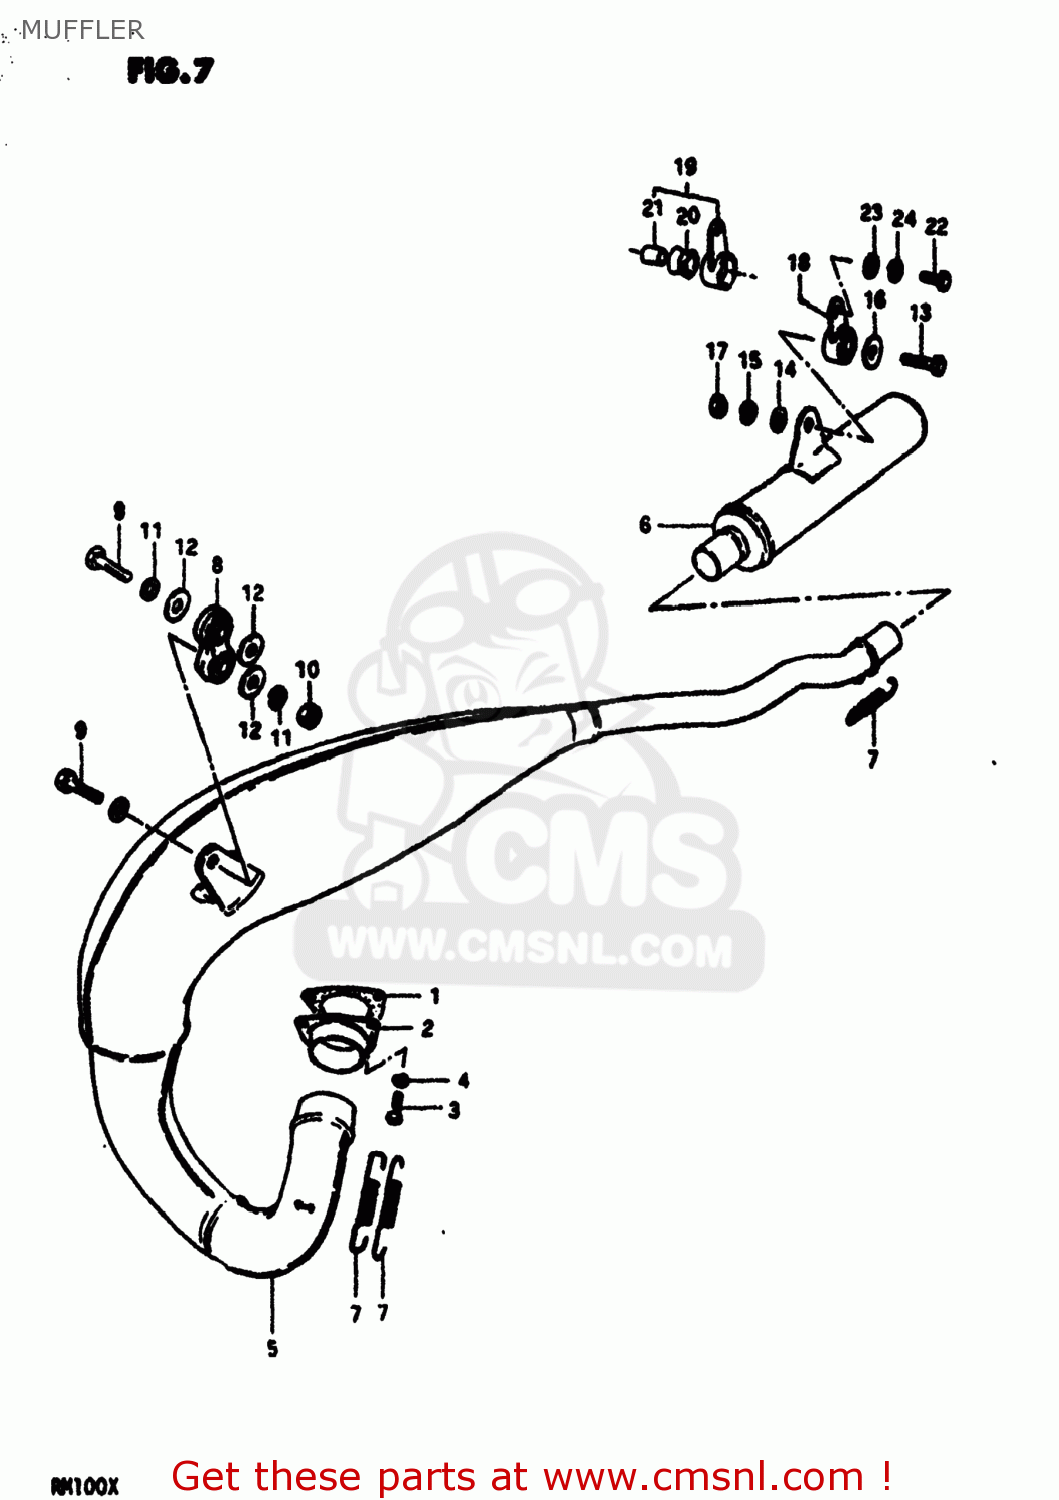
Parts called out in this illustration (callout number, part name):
1	GASKET,EXHAUST PIPE (MCA)
2	FLANGE,EXHAUST PIPE
3	SCREW
4	LOCK WASHER
5	BODY,MUFFLER
6	BODY,MUFFLER
7	SPRING
8	DAMPER,MUFFLER
9	BOLT
10	NUT
11	LOCK WASHER
12	WASHER
13	BOLT (8X30)
14	WASHER
15	LOCK WASHER
16	WASHER (8.5X29X1.6)
17	NUT
18	DAMPER,MUFFLER SUPPORT
19	DAMPER,MUFFLER SUPPORT 2ND
20	CUSHION
21	SPACER (8.2X12X17)
22	BOLT
23	WASHER
24	LOCK WASHER
